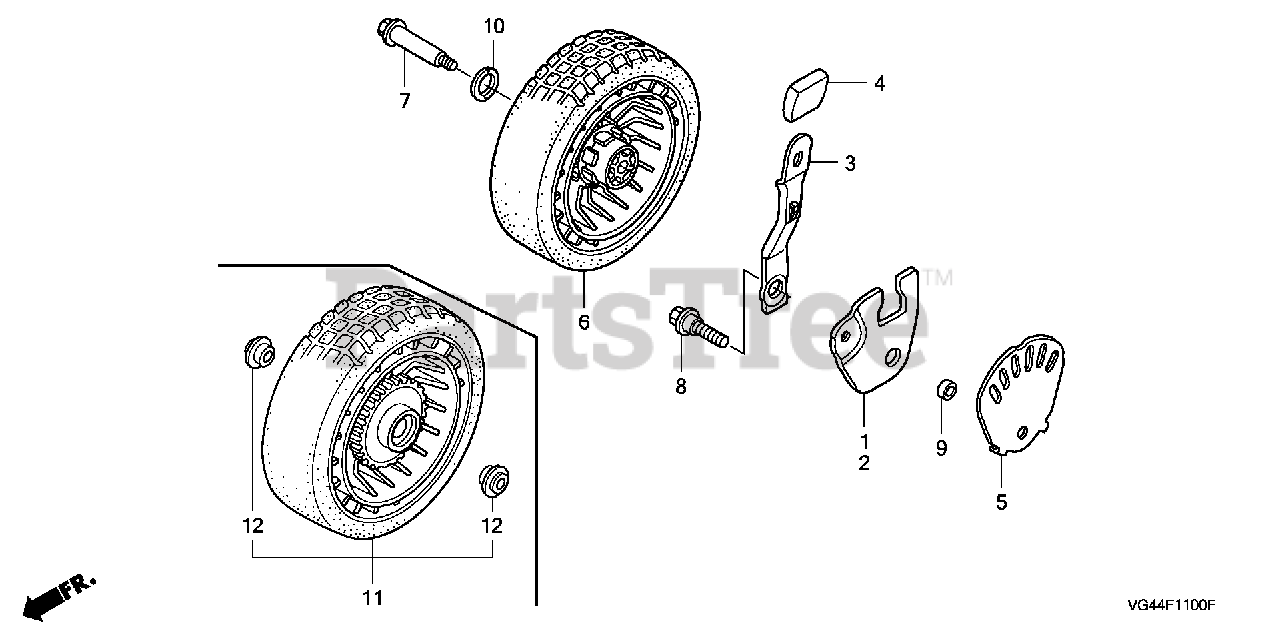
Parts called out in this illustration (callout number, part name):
1	ARM, R. FR. ADJUSTING
2	ARM, L. FR. ADJUSTING
3	PLATE, FR. ADJUSTER
4	GRIP, ADJUSTER
4	GRIP, ADJUSTER *NH105* (MAT BLACK)
5	PANEL, FR. ADJUSTER
6	WHEEL, FR.
7	BOLT, FR. WHEEL SHAFT
8	BOLT, ADJUSTER ARM
9	COLLAR, FR. ADJUSTING
10	WASHER, WHEEL
